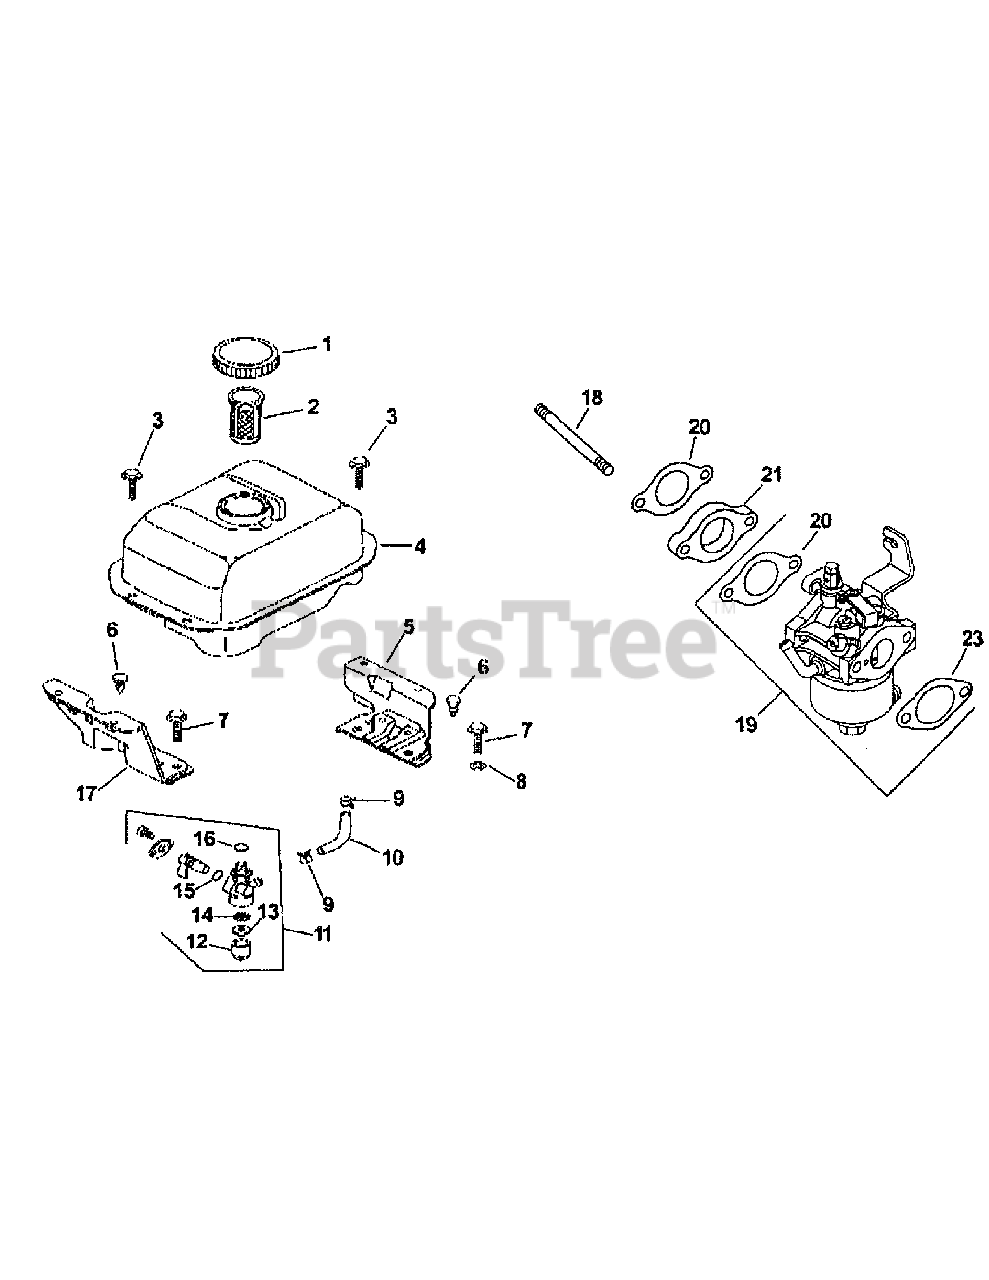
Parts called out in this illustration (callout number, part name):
1	Cap, Fuel Tank
4	Tank, Fuel
5	Bracket, Fuel Tank
11	Valve, Fuel
13	Gasket
14	Filter, Screen
16	Gasket
17	Bracket, Fuel Tank
18	Stud, Carburetor
19	Kit, Carburetor
20	Gasket, Intake
21	Manifold, Intake
23	Gasket, Air Cleaner
